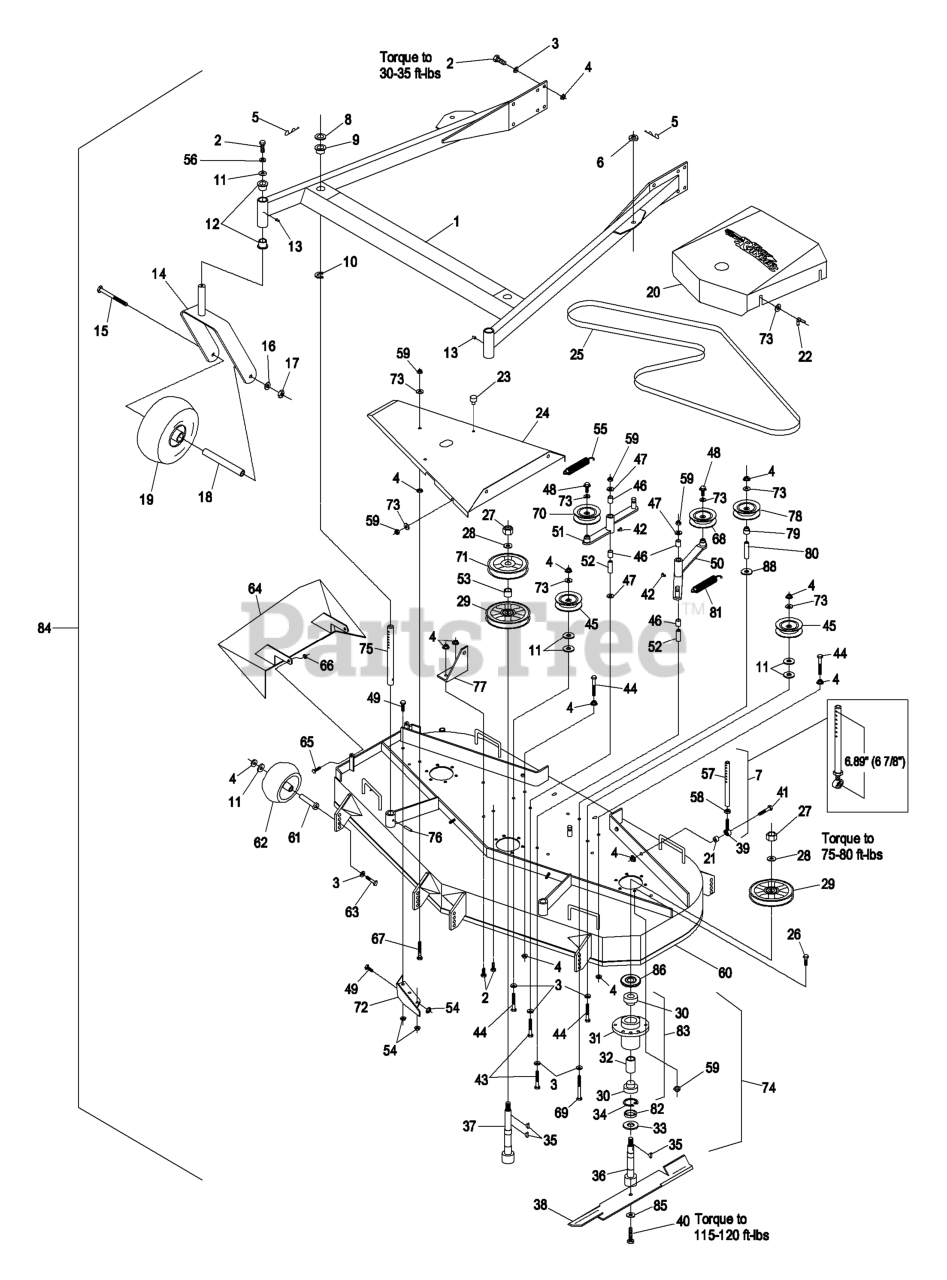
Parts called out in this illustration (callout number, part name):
1	SUPPORT ASSY-FMD60
2	SCREW-HH
3	WASHER-BELLEVILLE
4	NUT-HHF, WHIZ
5	Hairpin, .177
8	SPACER-DECK SUPPORT
9	BUSHING-DECK
10	RING-RETAINING
11	WASHER
12	BEARING-FLANGED
13	FITTING-GREASE
15	SCREW-HH
16	WASHER-LOCK
17	NUT-HH
22	NUT-WING
24	WLD,DECK COVER
25	BELT-DRIVE, BLADE
26	SCREW-HH
27	NUT-HEX
28	WASHER-SPRING
29	SHEAVE,BLADE DRIVE
30	BEARING
32	SPACER-BEARING
33	GUARD-BEARING, BOTTOM
34	RING-SNAP
35	KEY-WOODRUFF
36	SHAFT,SPINDLE SHORT
39	BALLJOINT
40	SCREW-CAP
41	SCREW-HH
42	FITTING-GREASE, 90 DEG
43	SCREW-HH
44	SCREW-HH
45	IDLER,PULLEY
46	SLEEVE-BEARING
47	WASHER-FLAT
48	Bolt, Whizlock 3/8-16 X 1
49	SCREW-HH
50	Arm, Deck Drive Idler
52	BUSHING-PIVOT, IDLER
53	SPACER-TUBE
55	SPRING-EXTENSION
56	WASHER-LOCK
57	LINK,SUPPORT
58	NUT-HEX
59	NUT-LOCK, NI
61	BUSHING-ROLLER
62	ROLLER-SCALP, ANTI
63	SCREW-HH
65	SCREW-HH
66	NUT-LOCK, NI
68	PULLEY-IDLER
69	SCREW-HH
70	IDLER,PULLEY
72	WLD,BAFFLE DISCHARGE
73	WASHER-FLAT
74	ASM,CUTTER HSG SERVICE
75	ROD,DECK SUPPORT
77	BRACKET,SPRING ANCHOR
78	PULLEY-IDLER
79	BUSHING,IDLER
80	SPACER-FENDER
81	SPRING-EXTENSION
82	SPACER-PULLEY/BEARING
85	WASHER-BLADE BOLT, HEAVY
86	GUARD,BEARING TOP .880
87	KIT, SP CASTER WHEEL REPL
88	WASHER
